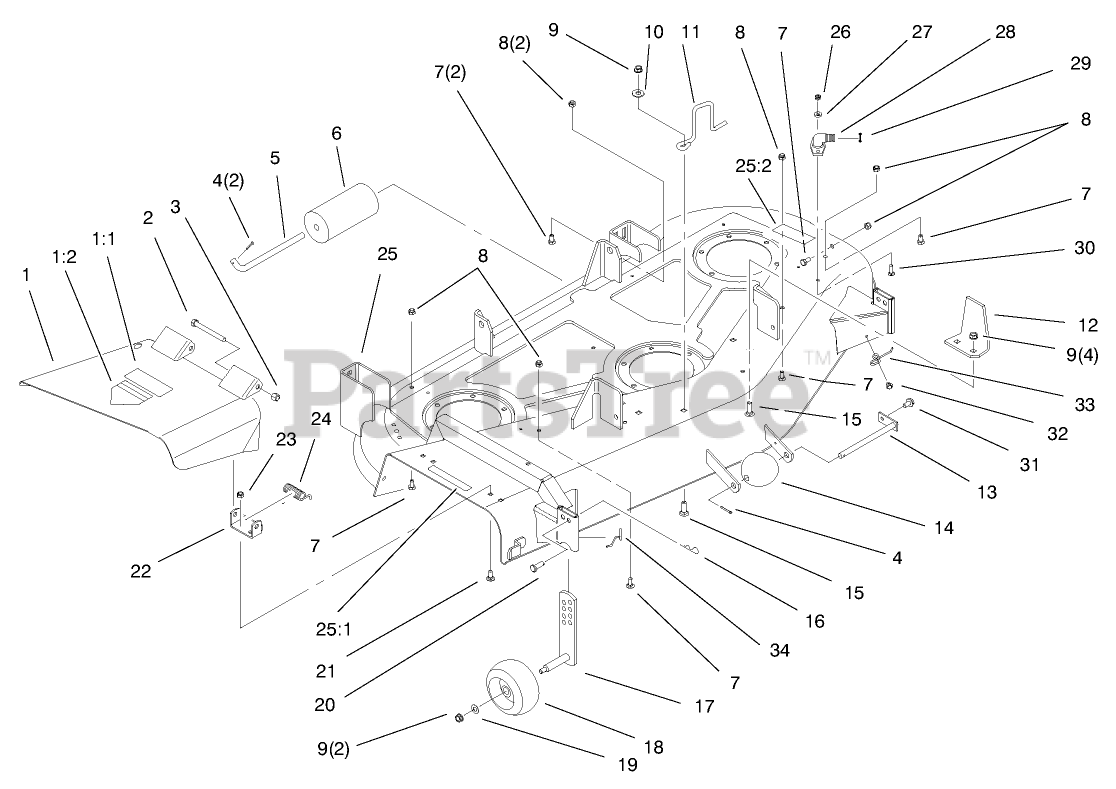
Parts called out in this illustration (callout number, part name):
1	DEFLECTOR/DECAL ASM-INTL
1:1	DECAL-DANGER
1:2	DECAL-DANGER
2	SCREW-HH
3	NUT-HEX
4	PIN-COTTER
5	SHAFT-ROLLER, REAR
6	ROLLER-DECK
7	SCREW-HH
8	NUT-LOCK, NI
9	NUT-LOCK, NI
10	WASHER
13	SHAFT ASM
14	ROLLER
15	BOLT-CARR
16	PIN-HAIR
17	GAGE-WHEEL
19	WASHER-FLAT
20	PIN-CLEVIS
21	SCREW-CARR
22	BRACKET-PIVOT
23	NUT-LOCK, NI
24	SPRING
25:1	DECAL-CAUTION
25:1	DECAL-DANGER
25:2	DECAL-DANGER
26	NUT-LOCK, NI
27	WASHER-FLAT
29	O-RING
30	BOLT-CARR
31	SCREW-HWHTF
32	SCREW-HHFTF
34	SPRING-GAGE WHEEL, RH
